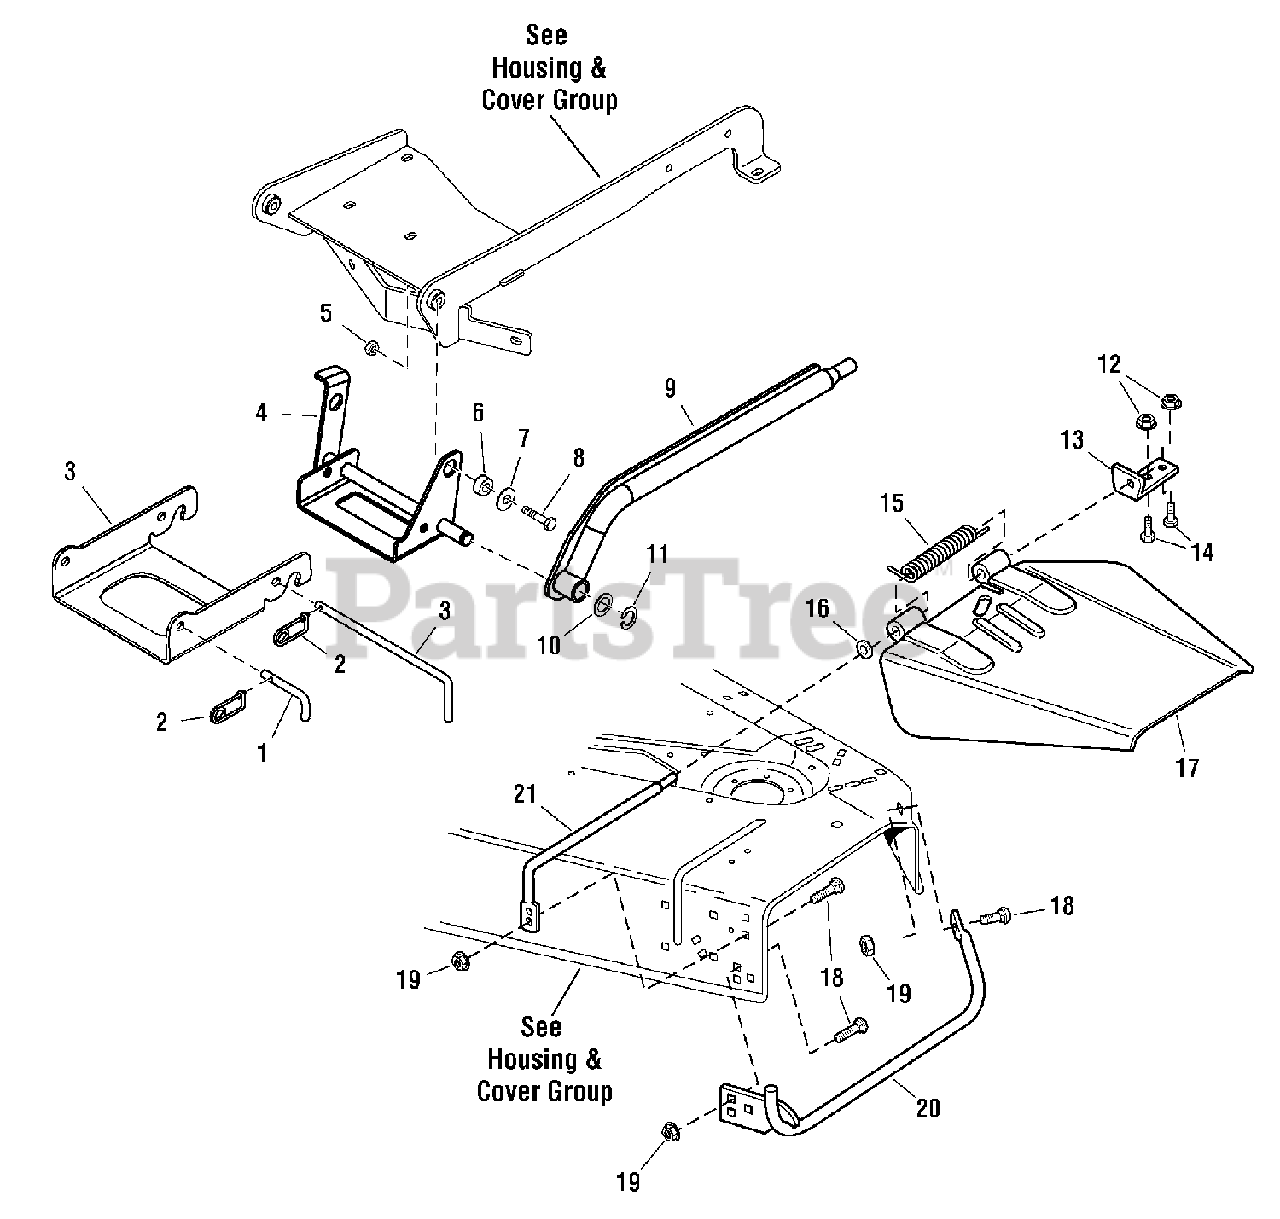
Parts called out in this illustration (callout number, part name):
2	PIN, Retainer, Spring
4	HITCH ASSEMBLY
5	NUT, Hex Top Flange Lock, 3/8-16
7	WASHER, 3/8
8	CAPSCREW, Hex Head, 3/8-16 x 1-3/4, Black
9	ARM ASSEMBLY
10	WASHER, 1, Black
11	RING, Retaining, External, 1, Black
12	NUT-HEX FLANGE 3/8-16 ESNA BLK
13	BRACKET
14	CAPSCREW, Hex Head, 3/8-16 x 1, Black
15	SPRING, Torsion
16	WASHER, 7/16, Black
17	DEFLECTOR & HING ASSEMBLY, Orange
17	DEFLECTOR & HING ASSEMBLY, Red
18	CARRIAGE BOLT, 3/8-16 x 1, Black
20	STONE GUARD & BRACKET ASSEMBLY
